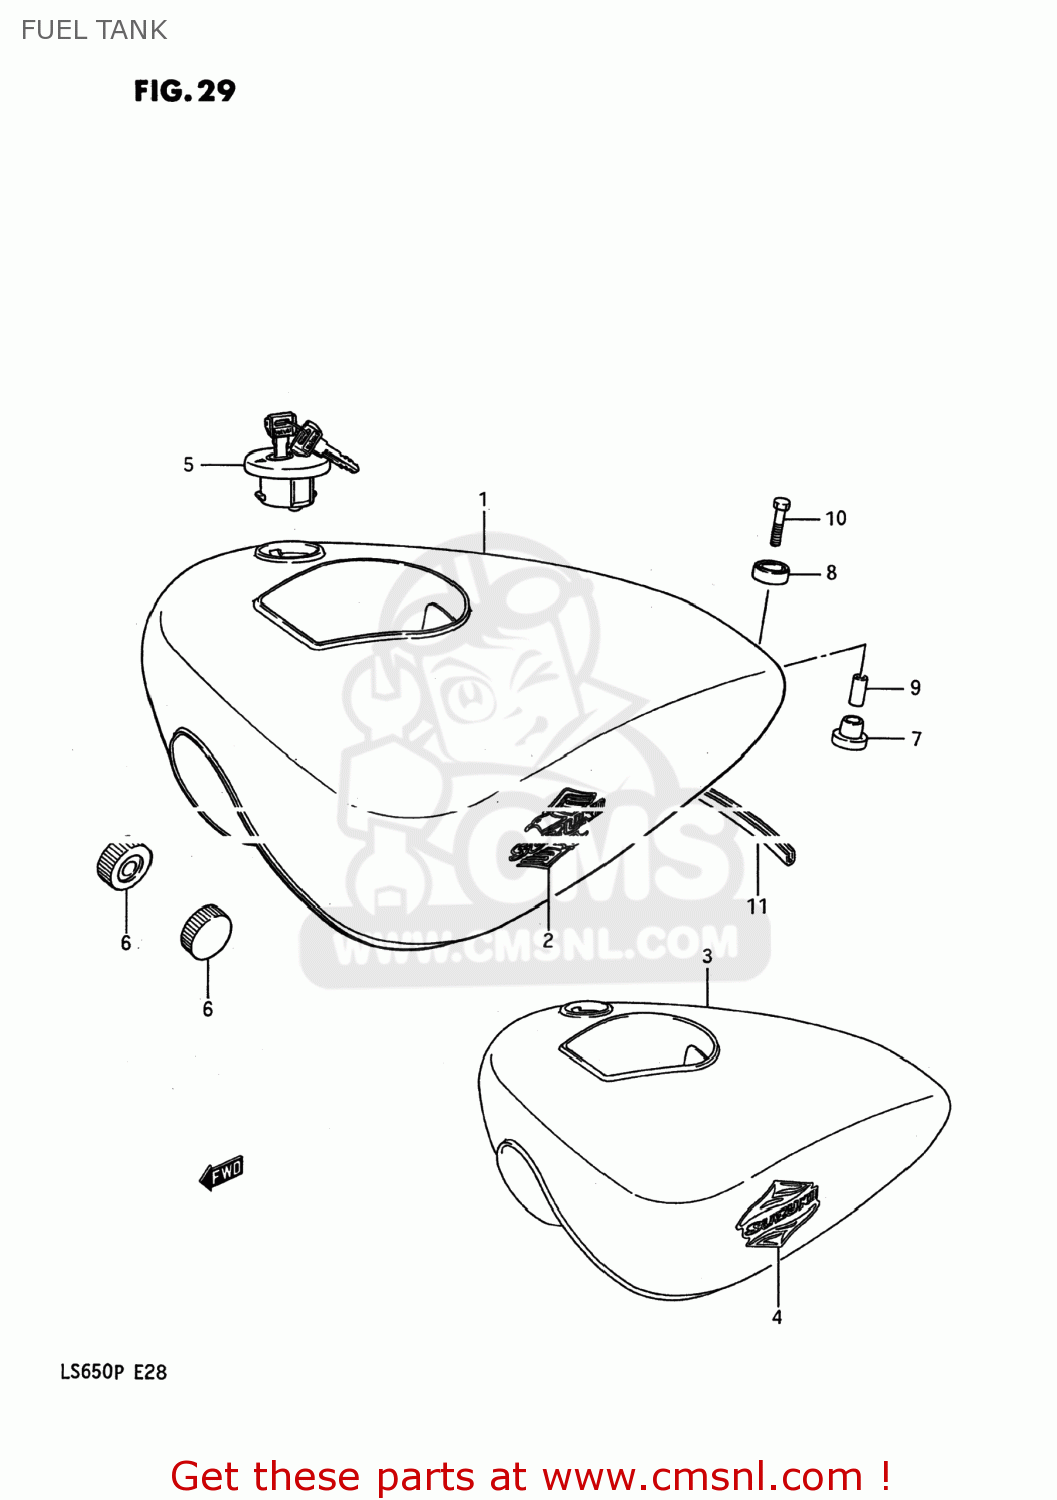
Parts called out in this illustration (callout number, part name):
1	TANK ASSEMBLY,FUEL
2	EMBLEM
3	TANK ASSEMBLY,FUEL
4	EMBLEM (BLUE)
5	CAP SET,FUEL TANK
6	CUSHION
7	CUSHION
8	CUSHION
9	SPACER
10	BOLT
11	MOLDING,FUEL TANK RR
